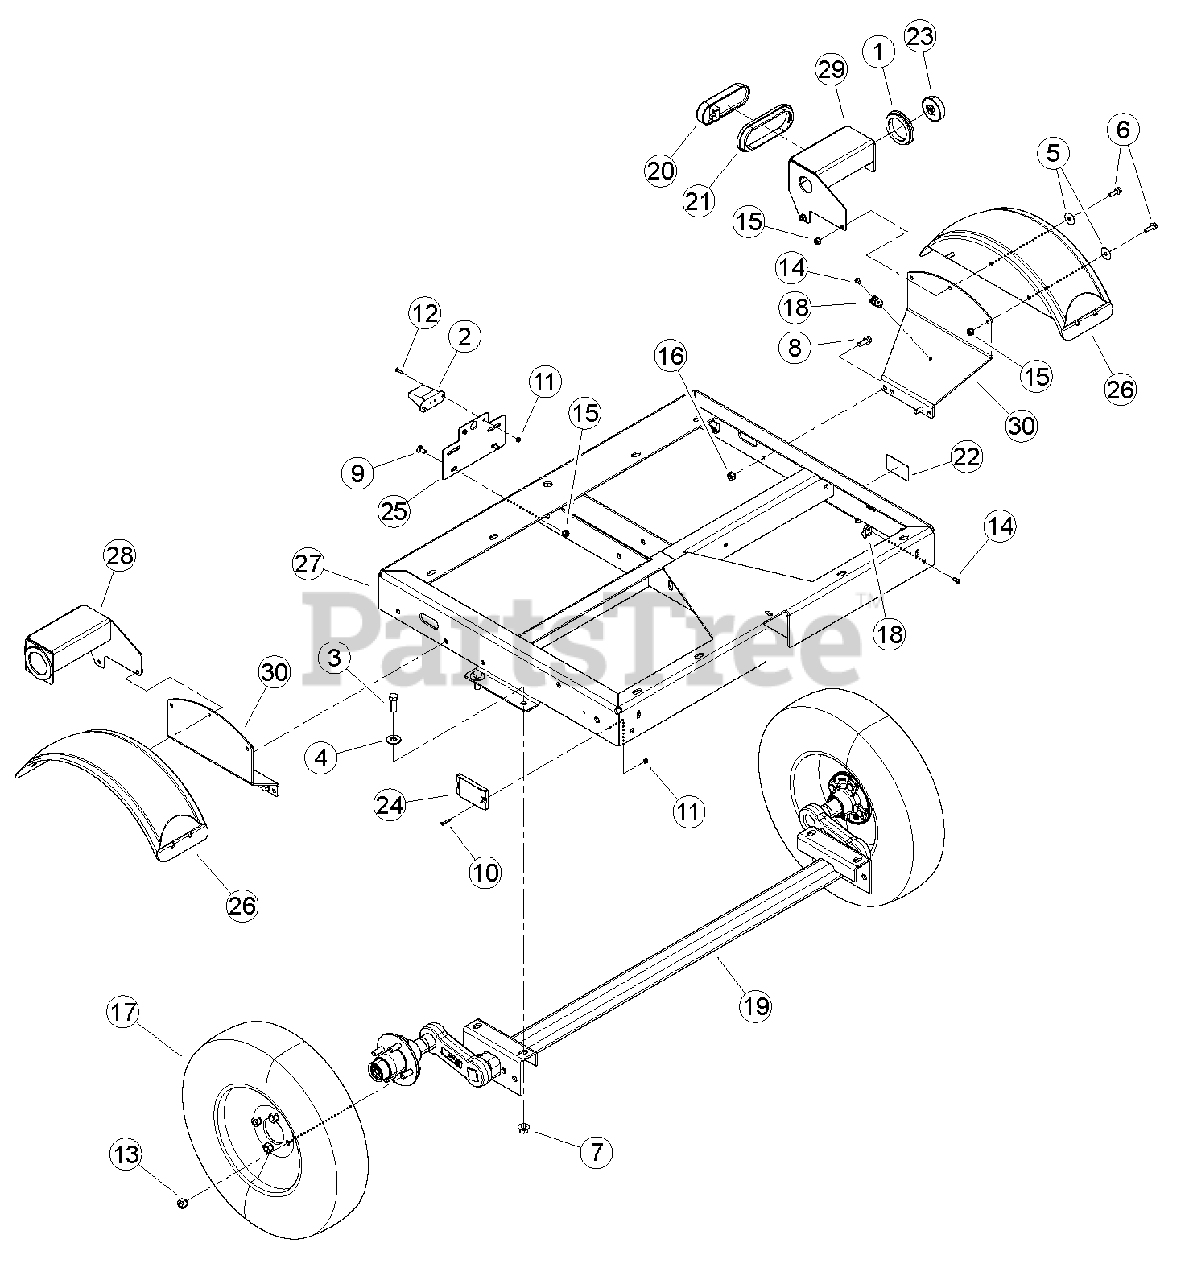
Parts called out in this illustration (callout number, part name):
1	GROMMET, CLEARANCE LIGHT
2	LIGHT, LICENSE PLATE
3	BOLT, 1/2-13 X 1-1/2 HEX HD GR5
4	WASHER, 1/2 FLAT
5	WASHER, 5/16" FENDER ZP
6	BOLT, 5/16 X 1 FLANGE NC
7	NUT, 1/2-13 NYLOCK FLANGE
8	BOLT, 3/8 X 1 FLANGE NC
9	BOLT, 5/16 X 3/4 GR5 CRG NC ZP
10	SCREW, MCH 10-24 X 1" RND HD PHL ZP
11	NUT, 10/24 NYLOCK TYPE NM ZP
12	SCREW, MCH #10-24 X 3/4" PAN HD PH ZP
13	NUT, 1/2-20 WHEEL
14	RIVET, AL BLIND 1/4 X 3/4 DOME HEAD
15	NUT, 5/16-18 NYLOCK FLANGE
16	NUT, 3/8-16 NYLOCK FLANGE
17	ASSEMBLY, 5.30-12 TIRE + SPOKE RIM
18	CLAMP, CABLE MOUNT
19	AXLE, 2000 LB TORSION
20	TAIL LIGHT, OVAL LED
21	GROMMET, OVAL TAIL LIGHT
22	DECAL, 5.30-12 LOAD RATING
23	LIGHT, CLEARANCE/MARKER RND RED LED
24	KIT, LED AMBER LIGHT
25	PLATE, LICENSE
26	FENDER, BLACK PLASTIC DRILLED
27	WELDMENT, TRAILER BASE
28	BRACKET, LIGHT RH
29	BRACKET, LIGHT LH
30	MOUNT, FENDER
